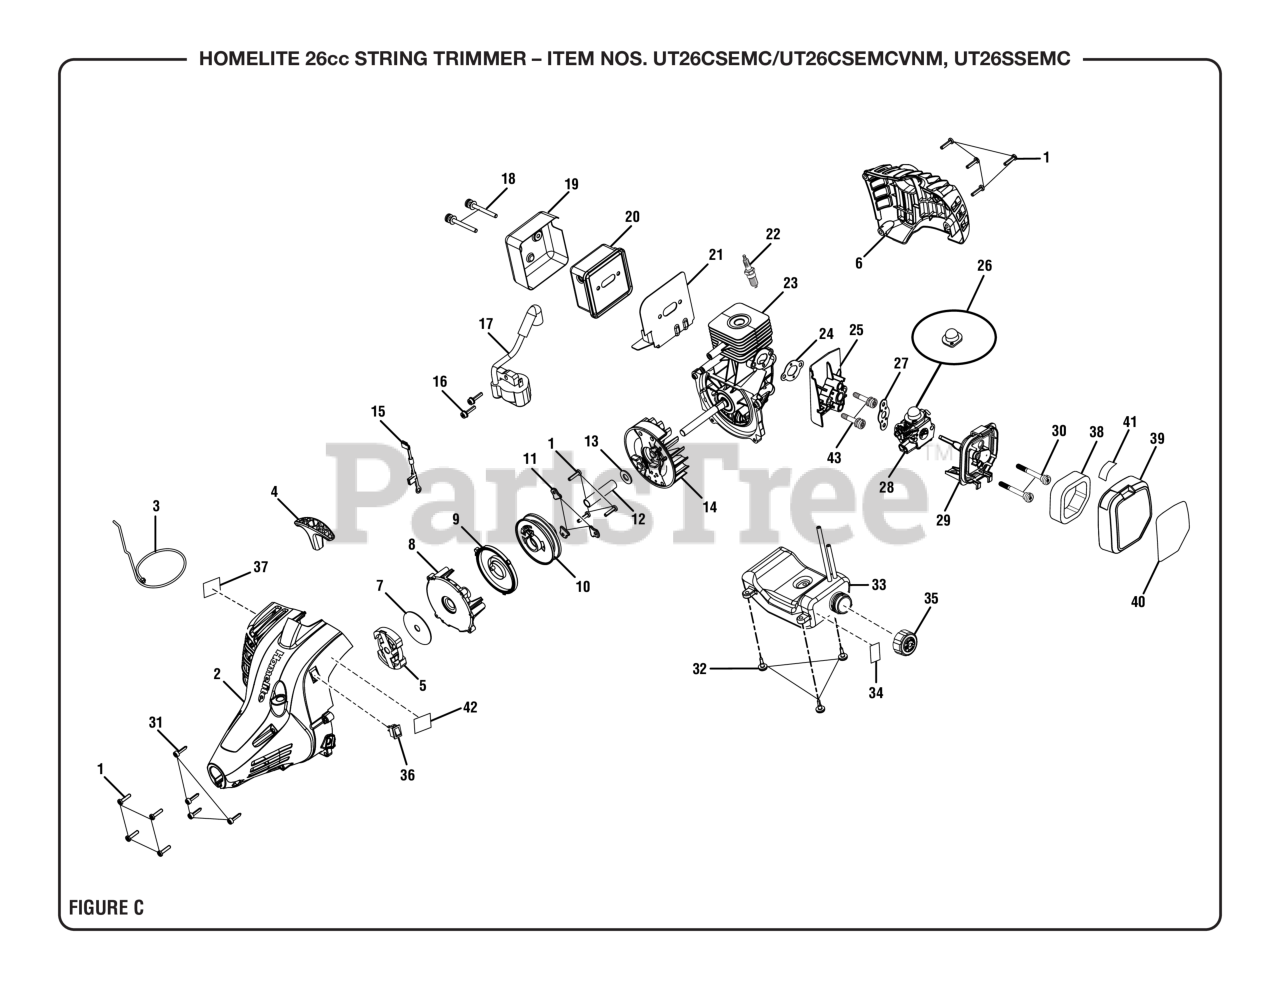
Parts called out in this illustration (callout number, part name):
1	Screw (M4 x 20 mm, T20 Torx Pan Hd. S.T.)
2	Starter Housing Assembly
3	Starter Rope (42 in.)
4	Pulley Handle
5	CLUTCH ASSEMBLY
6	Rear Housing
7	Washer (ID9.63 x OD50.75 x 1.10t)
8	Starter Housing
9	Spring & Container Assembly
10	Starter Pulley Assembly
11	Pulley Retainer
12	Spacer Tube
13	Washer (ID9.75 x OD20 x 1.6t)
14	Flywheel Assembly
15	Lead Assembly
16	Screw w/Washer (M4 x 19 mm, T20 Torx Pan Hd. S.T.)
17	Ignition Module
18	Screw w/Washers (10-24 x 2-1/8 in., T25 Torx Truss Hd.)
19	Muffler Housing
20	Muffler Assembly (Non "A" versions)
21	Muffler Gasket
22	SPARK PLUG CHAMPION - RCJ-6Y
23	Short Block Assembly
24	Inner Heat Dam Gasket
25	Heat Dam Deflector
28	Carburetor Assembly
29	Airbox Base Assembly
30	Screw (M5 x 45 mm, T20 Torx Truss Hd.)
31	Screw w/Washer (M4 x 16 mm, T25 Torx Truss Hd.)
32	Shoulder Screw w/Washer (M4 x 14 mm, T25 Torx Truss Hd.)
33	Fuel Tank w/Label & Cap Assembly
34	Fuel Tank Warning Label
35	Fuel Cap Assembly
36	Stop Switch (Momentary Contact)
37	Warning Label (Combustion)
38	Air Filter (Element)
39	Air Box Cover
40	Starting Label
41	Choke Label
42	Primer Bulb Location Label
43	Screw w/Washers (M5 x 30 mm, T25 Torx Pan Hd.)
